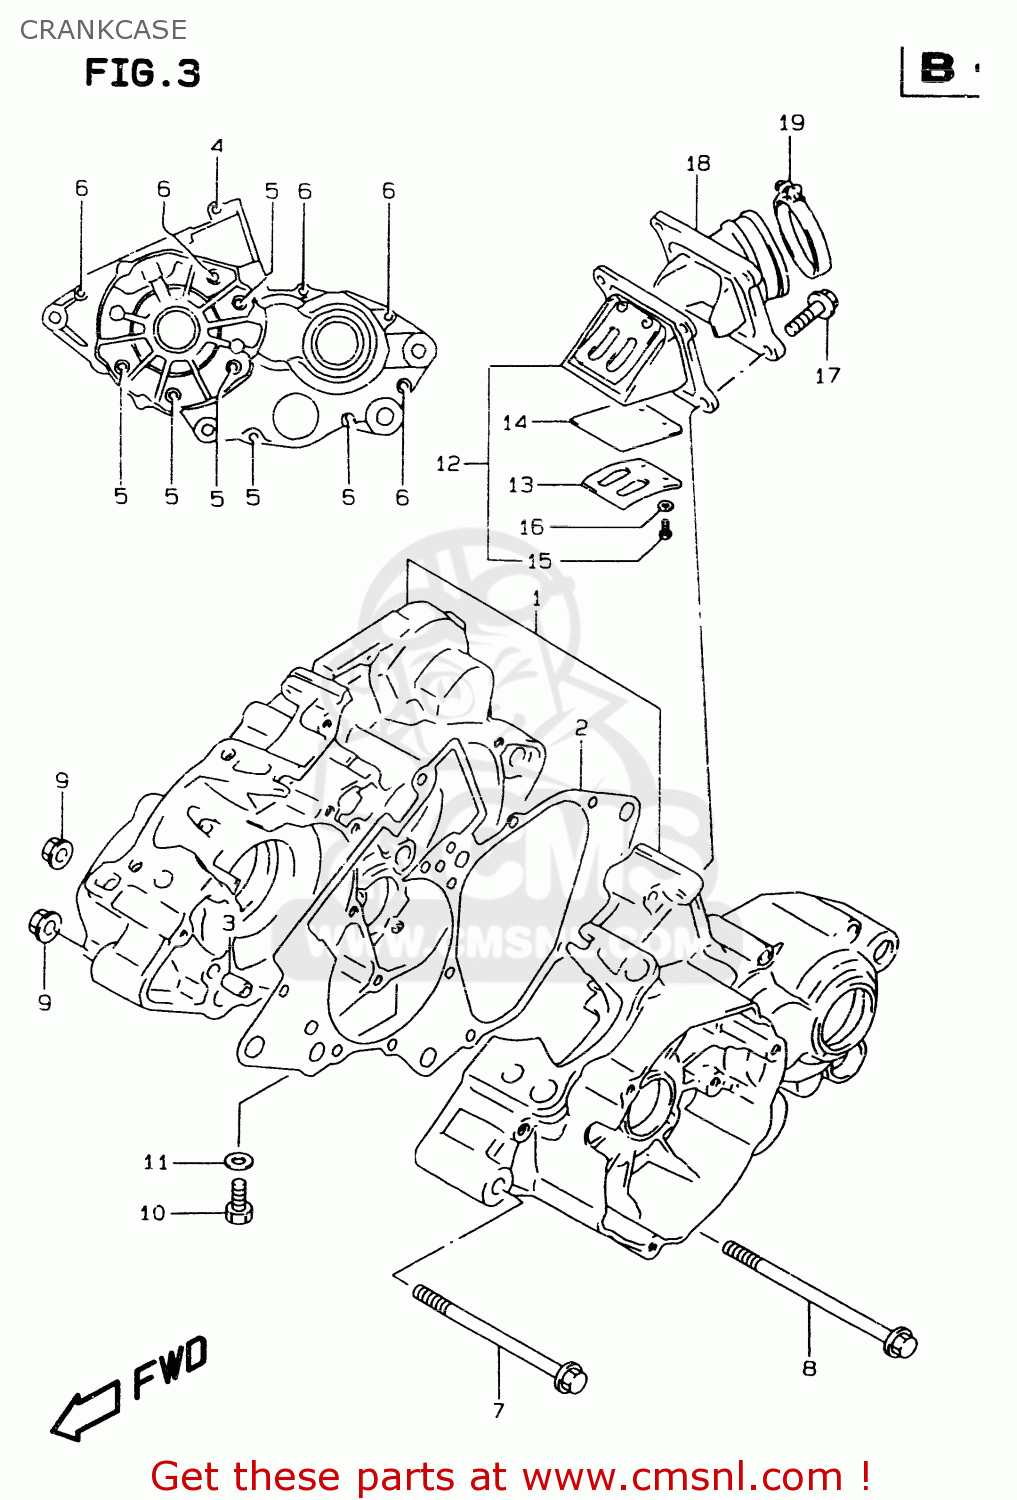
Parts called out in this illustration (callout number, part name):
1	CRANKCASE SET
2	GASKET,CRANKCASE (NAS)
3	PIN
4	BOLT
5	BOLT
6	BOLT
7	BOLT 8X92
8	BOLT(8X102)
9	NUT
10	BOLT
11	GASKET(8.2X14X1) (NAS)
12	VALVE ASSY,REED
13	STOPPER,REED VALVE
14	VALVE,REED
15	SCREW
16	WASHER,LOCK
17	SCREW
18	PIPE,INTAKE
19	CLAMP
